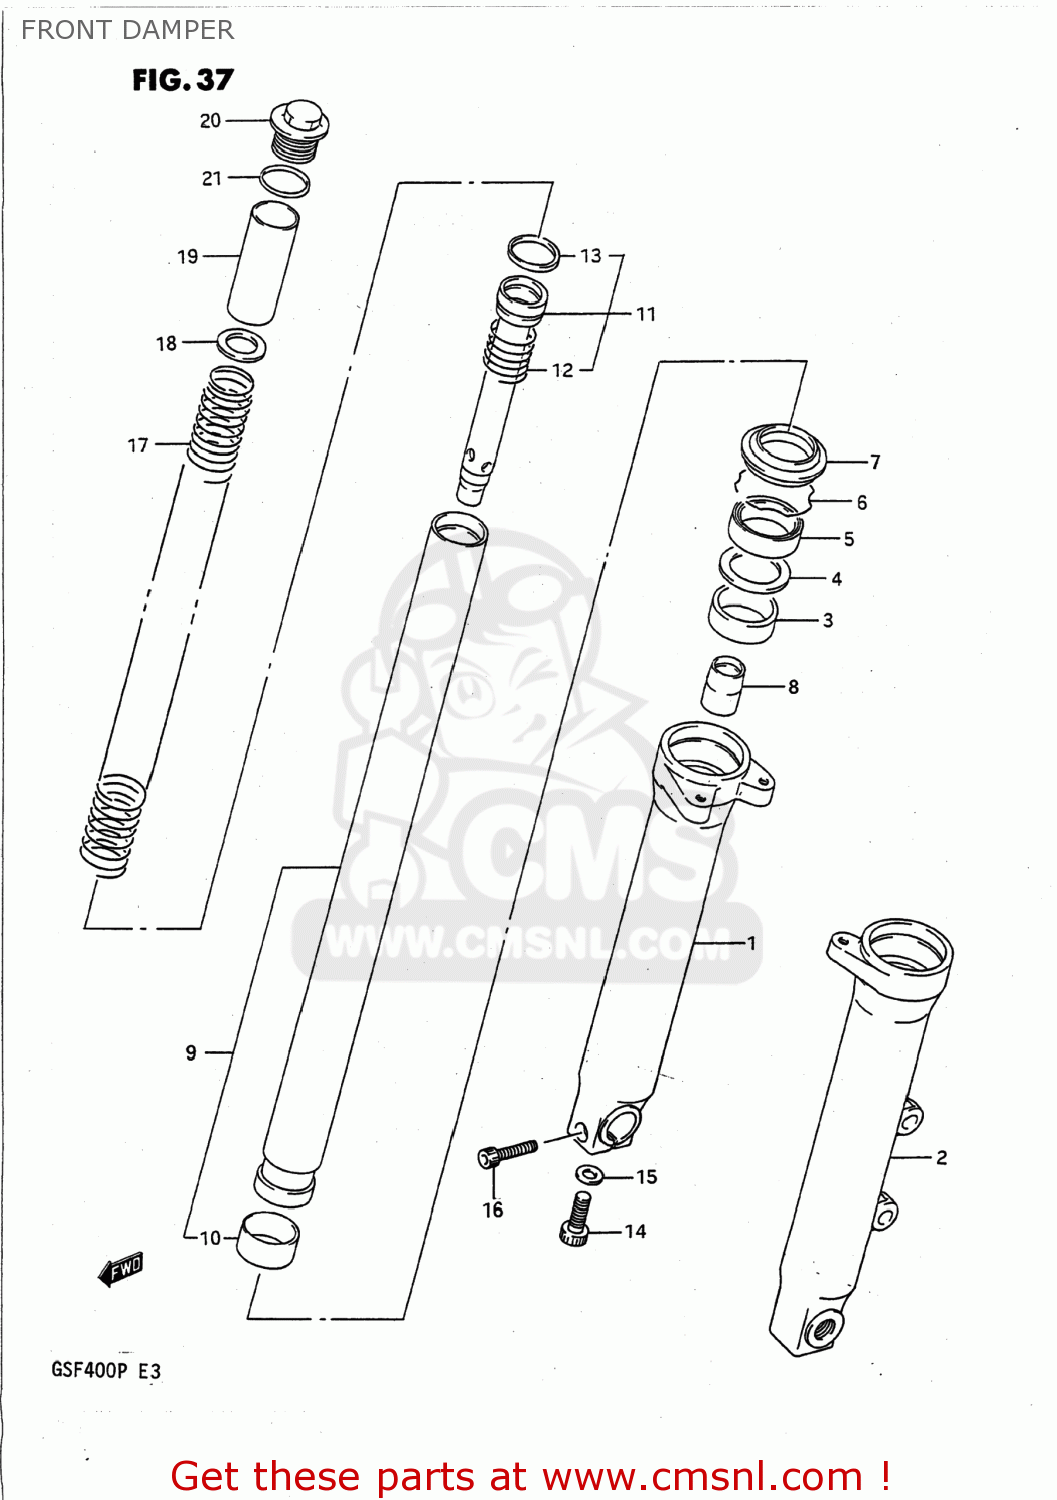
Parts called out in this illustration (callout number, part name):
1	TUBE,OUTER,RIGHT
2	TUBE,OUTER LH
3	METAL,SLIDE
4	WASHER,FORK OIL SEAL
5	OIL SEAL,FRONT FORK
6	RING,OIL SEAL STOPPER
7	DUST SEAL,FRONT FORK
8	PIECE,OIL LOCK
9	TUBE,INNER
10	PISTON
11	CYLINDER
12	SPRING,REBOUND
13	RING,PISTON
14	BOLT,FORK CYLINDER(10X25)
15	GASKET (NAS)
16	BOLT
17	SPRING,MAIN
18	GUIDE,SPRING
19	SPACER,SPRING
20	CAP,FORK
21	O-RING
